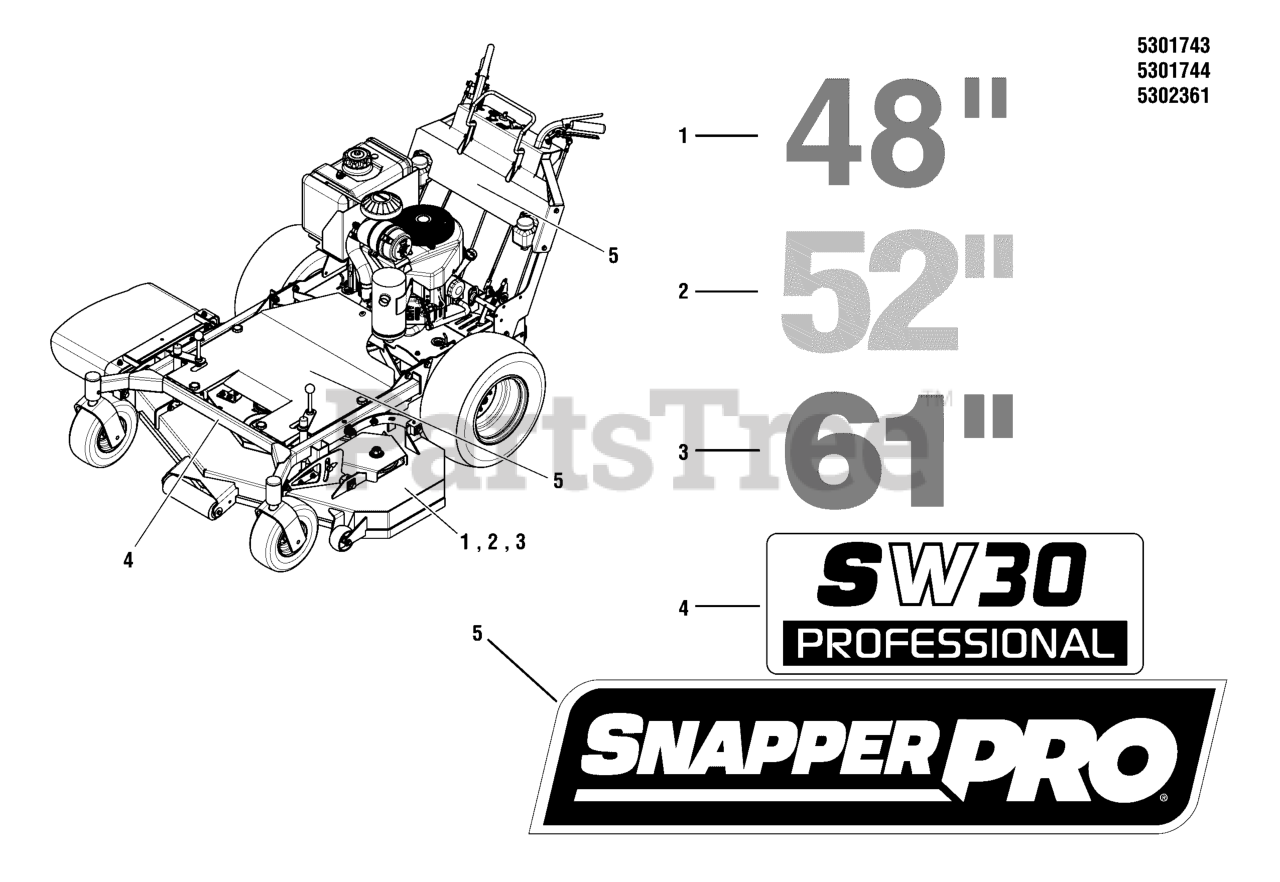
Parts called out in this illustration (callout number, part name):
1	DECAL, 48
2	DECAL, 52
3	DECAL, 61"
4	DECAL, SW30 (2014)
5	DECAL, SNAPPER PRO LOGO, LARGE
